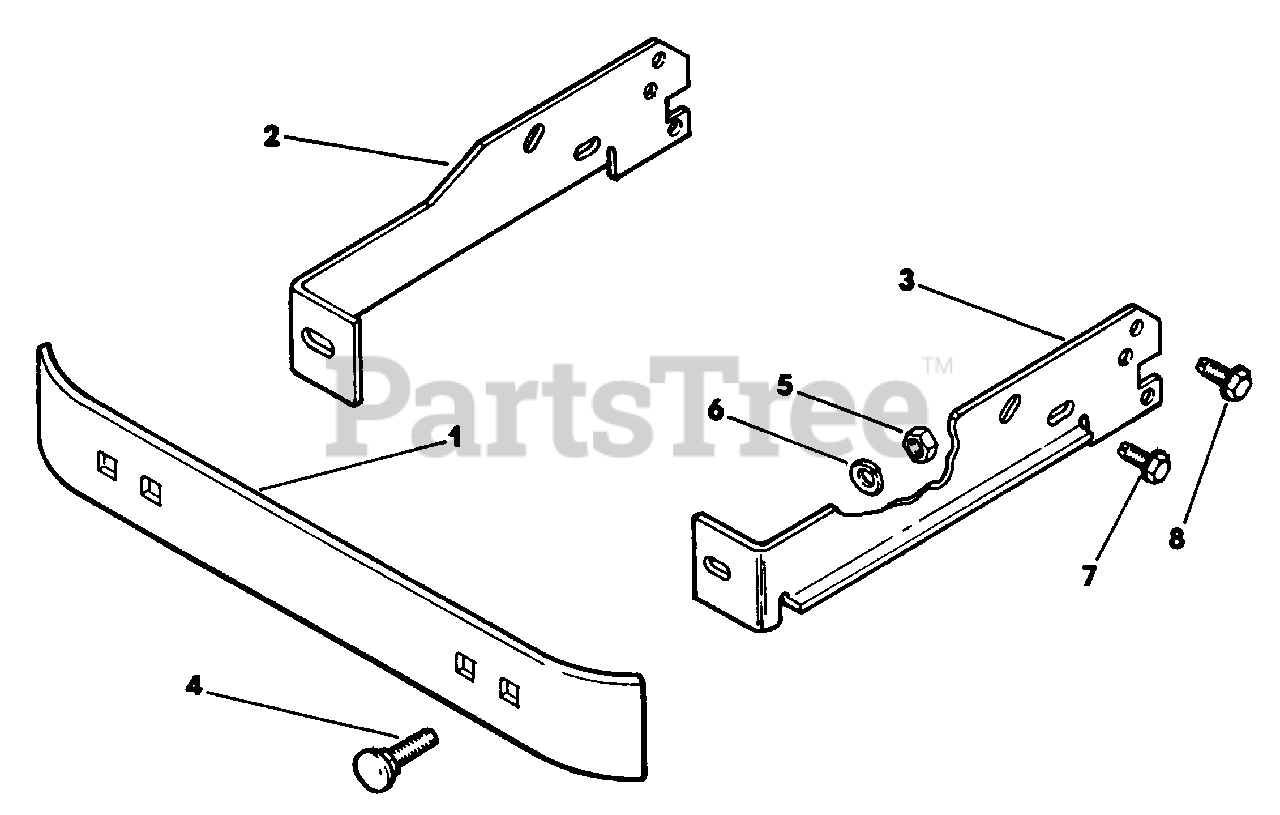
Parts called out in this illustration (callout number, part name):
1	Front Bumper
2	Bumper Side Support-R.H
3	Bumper Side Support-L.H
4	Bolt, Carriage
5	Nut, Hex
6	Washer, Spring Lock
7	Thread Forming Screw, Hex Hd
8	Thread Forming Screw, Hex Hd
